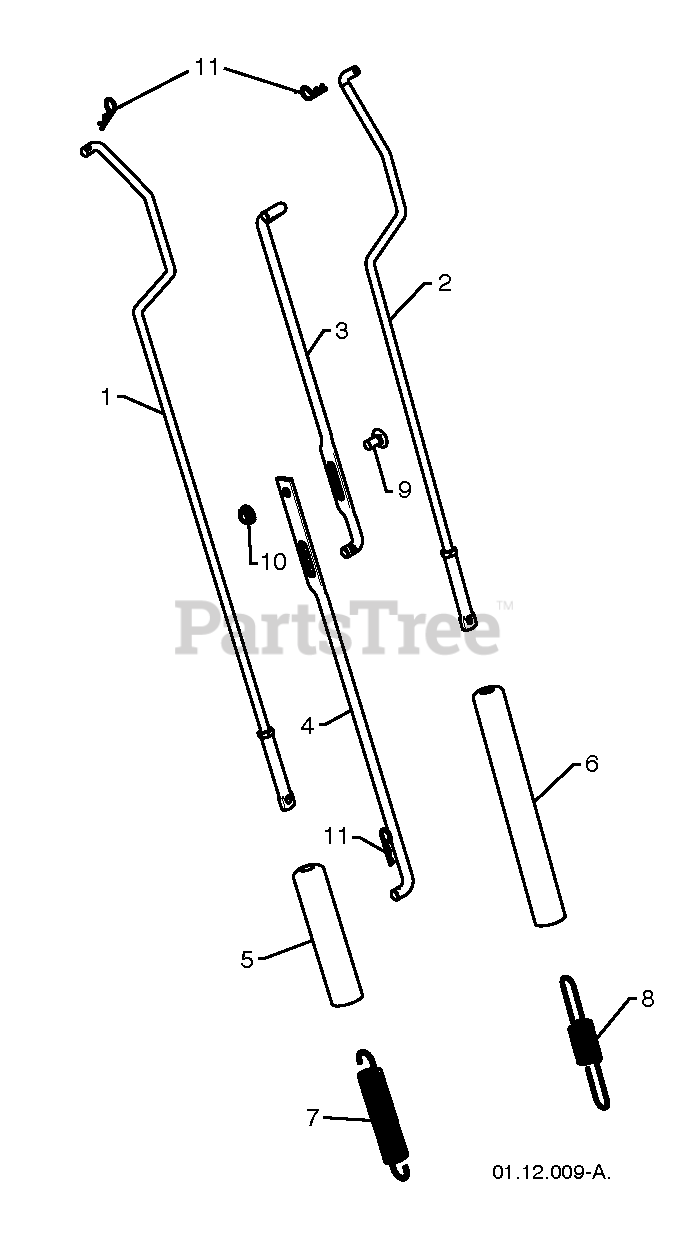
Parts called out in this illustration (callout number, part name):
1	ROD.IMPELLER.CONTROL.HYD.II.SN
2	ROD.TRACTION.CONTROL.SNOW
3	ROD.SHIFTER.TOP.HYD.SNOW
4	ROD, LOWER, SPEED CONTROL
5	SLEEVE, SPRING
6	SPRING.CONTROL.ROD.SNOW
7	SPRING.TRACTION.ROD.SNOW
8	SPRING, TRACTION DRIVE
9	BOLT
10	NUT.FLANGE.5/16
11	SPRING RETAINER
